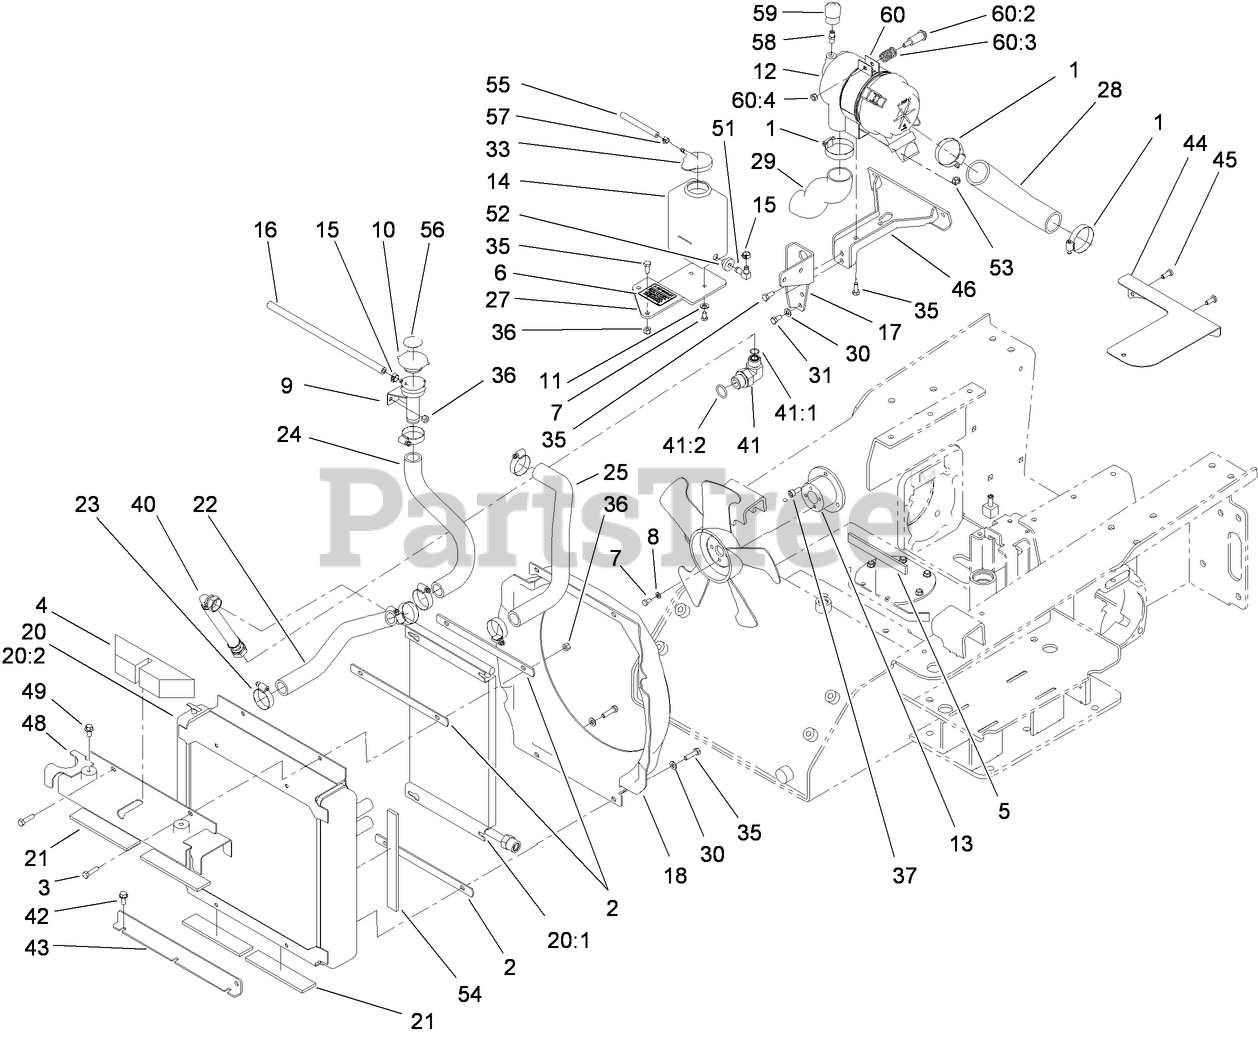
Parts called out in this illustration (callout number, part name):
1	CLAMP-HOSE
2	PLATE-BACKING
3	SCREW-HH
4	SEAL-FOAM
5	PAD-RUBBER
6	DECAL-RADIATOR FILL
7	SCREW-HH
8	WASHER-LOCK
9	TUBE-FILLER, RADIATOR
10	CAP-RADIATOR
11	WASHER-FLAT
12	AIR CLEANER ASM
13	SPACER-MACHINED
14	TANK-OVERFLOW
15	CLAMP-HOSE
16	HOSE-LP
17	MOUNT-FILTER, AIR
18	SHROUD-FAN
20	RADIATOR AND OIL COOLER ASM
20:1	COOLER-OIL, HYD
20:2	RADIATOR
21	PAD-RUBBER
22	HOSE-RADIATOR
23	CLAMP-HOSE
24	HOSE-RADIATOR
25	HOSE-RADIATOR
27	BRACKET-TANK, OVERFLOW
28	HOSE-AIR, INLET
29	HOSE-AIR
30	WASHER-PLAIN
31	BOLT
33	CAP-TANK, OVERFLOW
35	SCREW-HH
36	NUT-LOCK, NI
37	SCREW-CAP, HSH
40	HYD HOSE ASM
41	FITTING-ELBOW 90
41:1	O-RING
41:2	O-RING
42	SCREW-HWHTF
43	MOUNT-RADIATOR
44	PLATE-BAFFLE, STARTER
45	SCREW-HH
46	BRACKET ASM
48	BRACKET-RADIATOR
49	SCREW-HHF
51	FITTING-ELBOW-90
52	BUSHING
53	NUT-HF
54	FOAM-SEAL
55	HOSE-LP
56	DECAL-CAP, RADIATOR
57	CLAMP-HOSE
58	Nipple-Pipe
59	INDICATOR-MINI
60	AIR CLEANER MOUNTING BAND ASM
60:3	SPRING
60:4	NUT
